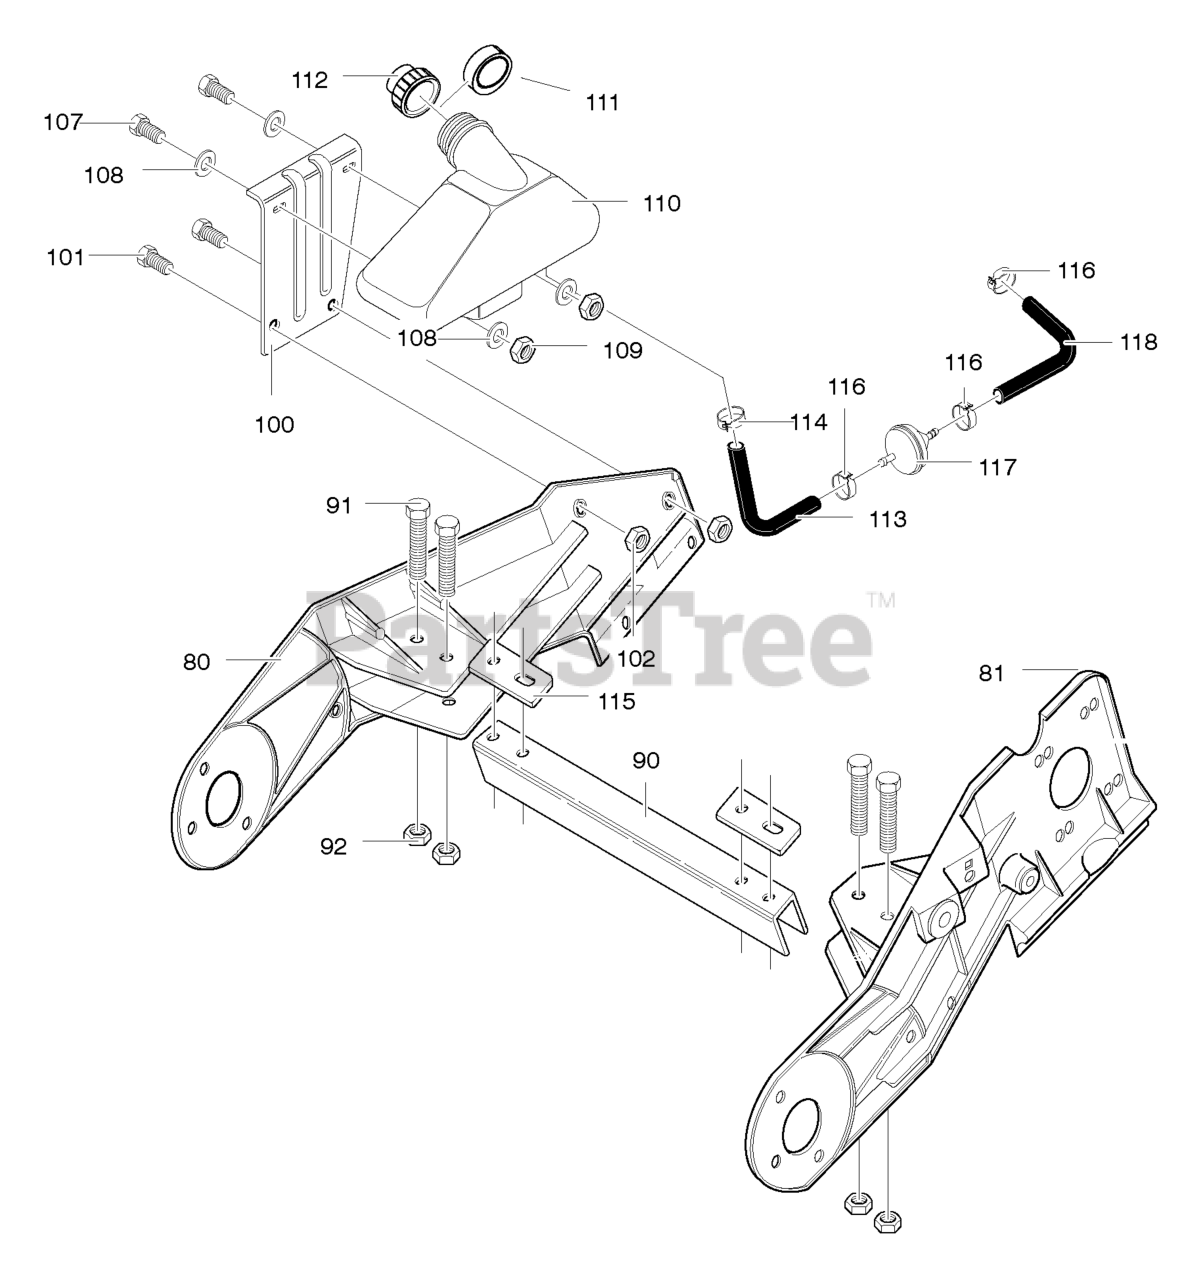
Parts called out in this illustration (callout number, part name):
80	FRAME, RIGHT SIDE
81	FRAME, LEFT SIDE
90	CHANNEL, FRAME
91	SCREW, 1/4-20X2.00
92	NUT, 1/4-20
100	BRKT, FUEL TANK
101	SCREW, 1/4-20X .75
102	NUT, 1/4-20
107	SCREW, 1/4-20X .75
108	WASHER, FLAT
109	NUT, 1/4-20
110	TANK, FUEL 1.5QT
111	RING, FUEL TANK
112	CAP, FUEL
114	CLAMP, HOSE
115	PLATE, SUPPORT
116	CLAMP, HOSE
117	FILTER, IN-LINE
